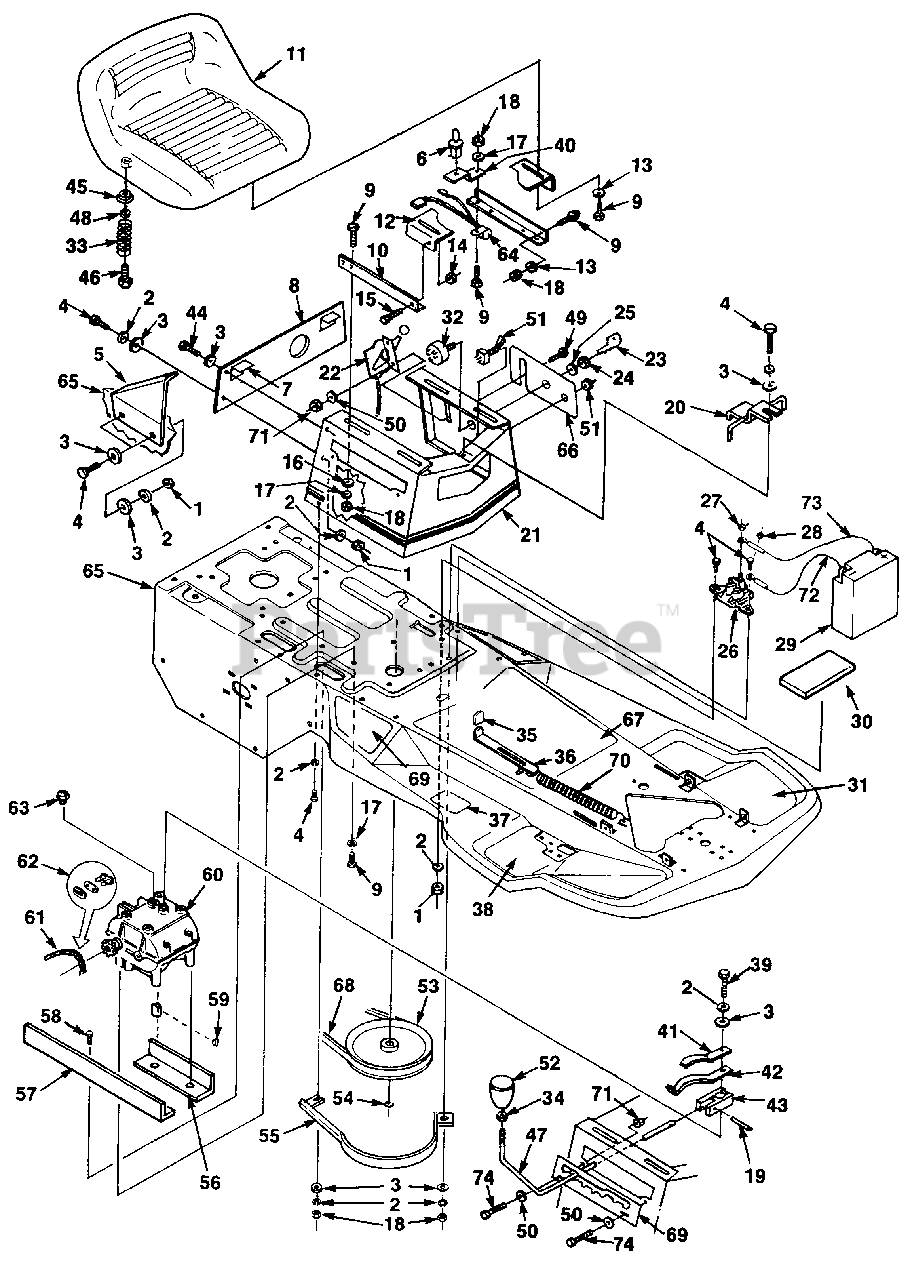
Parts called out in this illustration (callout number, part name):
1	NUT-Hex 1/4-20
2	WASHER-Lock 1/4
3	WASHER- Flat 1/4
4	BOLT- 1/4-20 x.625
5	BRACKET- Chain guard
6	SWITCH- Seat
8	PLATE- Reinforcement
9	BOLT- 5/16-18 x.750
10	SEAT RAIL
12	BRACKET- Seat
13	WASHER- Lock 5/16
14	NUT- Centerlock hex 5/16-18
15	BOLT- Shoulder 5/16-18 hex
16	WASHER- Plain 5/16
17	WASHER- Lock 5/16
18	NUT- 5/16-18 hex
19	PIN- Spring 3/16 x 1
20	BRACKET- Battery
21	TOWER- Seat
22	THROTTLE CONTROL & CABLE
23	KEY- Ignition
24	NUT- Ignition switch 5/8-32
25	WASHER- Ignition switch 5/8
26	SOLENOID- Switch
27	NUT
28	NUT
29	BATTERY
30	BATTERY PAD
31	FOOT REST (left hand)
32	IGNITION SWITCH
33	SPRING- Torsion
34	NUT- Hex jam 3/8-24
35	KNOB- Latch
36	LATCHING- Parking brake
38	FOOT REST (right hand)
39	SCREW- Hex hd. 1/4-28 x.750
40	BRACKET- Seat switch
41	SPRING- Flat (shift yoke)
42	SPRING- Flat (shift yoke)
43	BRACKET- Pivot
44	SCREW- Hex cap 1/4-20 x 3/4
45	RETAINER- Spring
46	SCREW- Hex hd. 5/16-18 x 3/4
47	GEARSHIFT LEVER
48	LOCKWASHER 5/16
50	WASHER- Flat 1/4
51	SWITCH- P.T.O.
52	KNOB- Shift lever
53	TRANSMISSION PULLEY
54	RING-Snap
55	BELT GUARD- Transmission
56	ANGLE- Short
57	ANGLE- Long
58	BOLT- 1/4-20 x 3/4
59	KEY- Transmission 3/16 x 3/4
60	TRANSMISSION- Peerless Tecumseh
61	Chain- Drive #40
62	CONNECTING LINK- Chain
63	SWITCH- Neutral safety
64	NEUTRAL START SAFETY INTERLOCK
66	DECAL- Control Manual
67	DECAL- Instruction
68	BELT- Transmission
69	PLATE- Shift
70	SPRING- Extension
72	CABLE- Ground
73	CABLE- Battery
74	SCREW- 10-24 x 1/2
